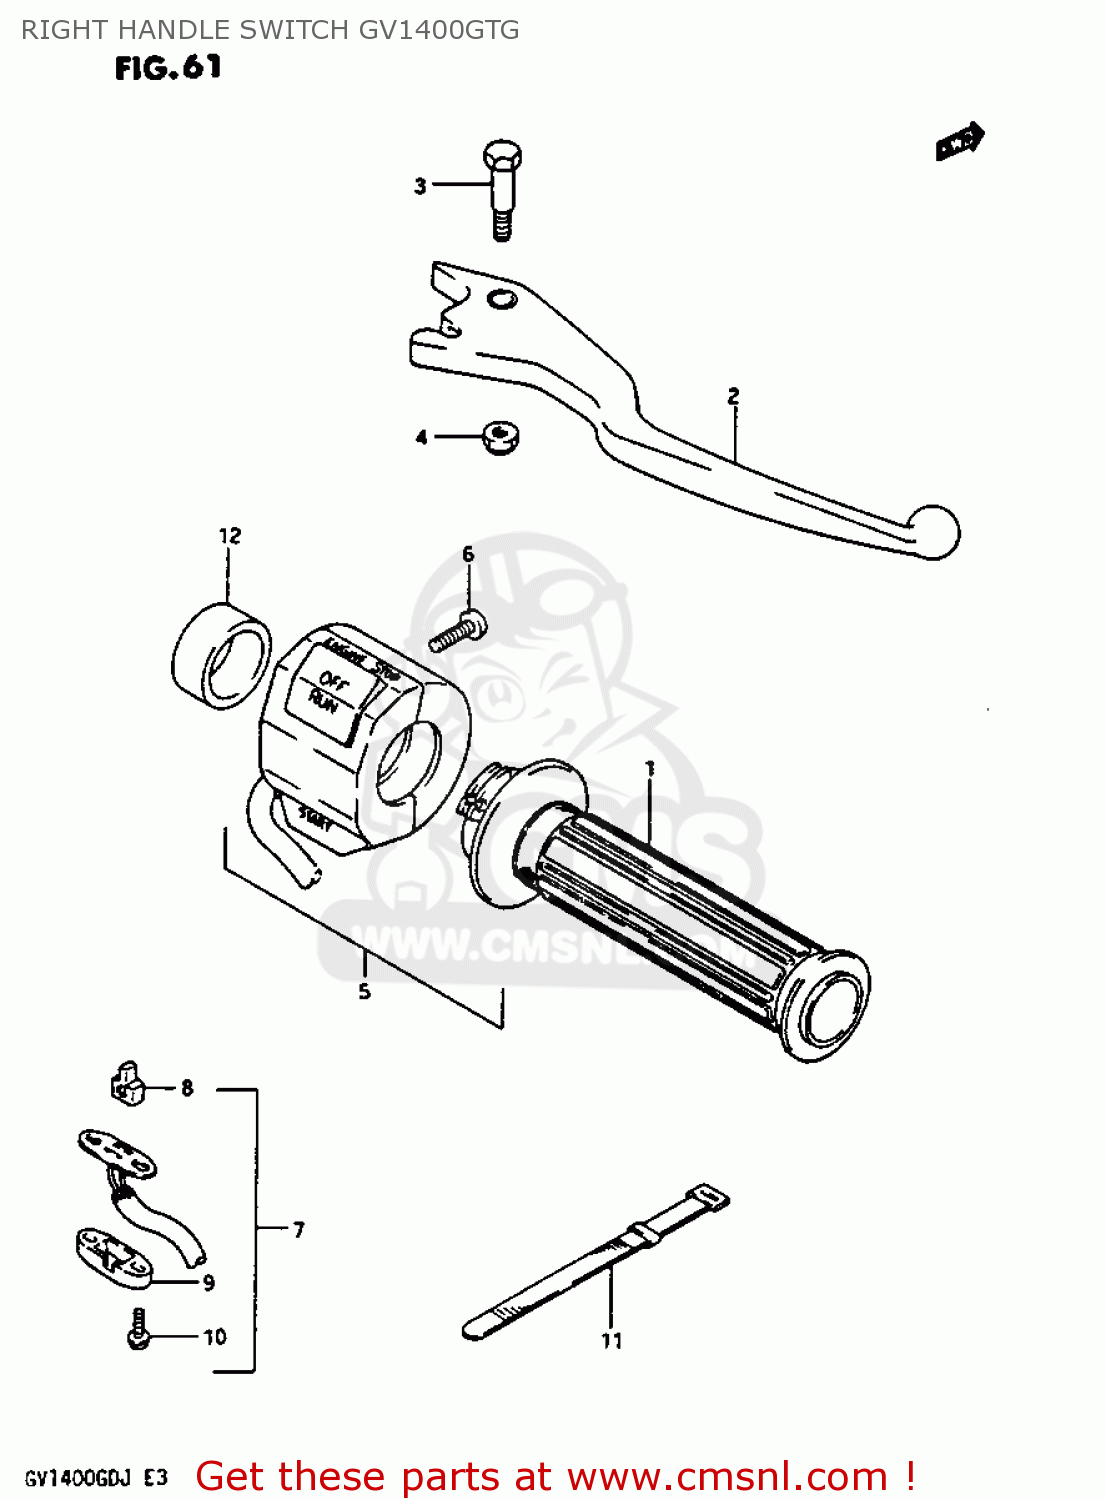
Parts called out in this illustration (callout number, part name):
1	GRIP,THROTTLE
2	LEVER,BRAKE
3	BOLT,LEVER
4	NUT
5	SWITCH ASSY,HANDLE RH
6	SCREW 5X20
7	SWITCH ASSEMBLY
8	CONTACT,SWITCH
9	COVER,FR BK TERMINAL BASE
10	SCREW
11	CLAMP(L:187)
12	BOLT,MASTER CYLINDER H
